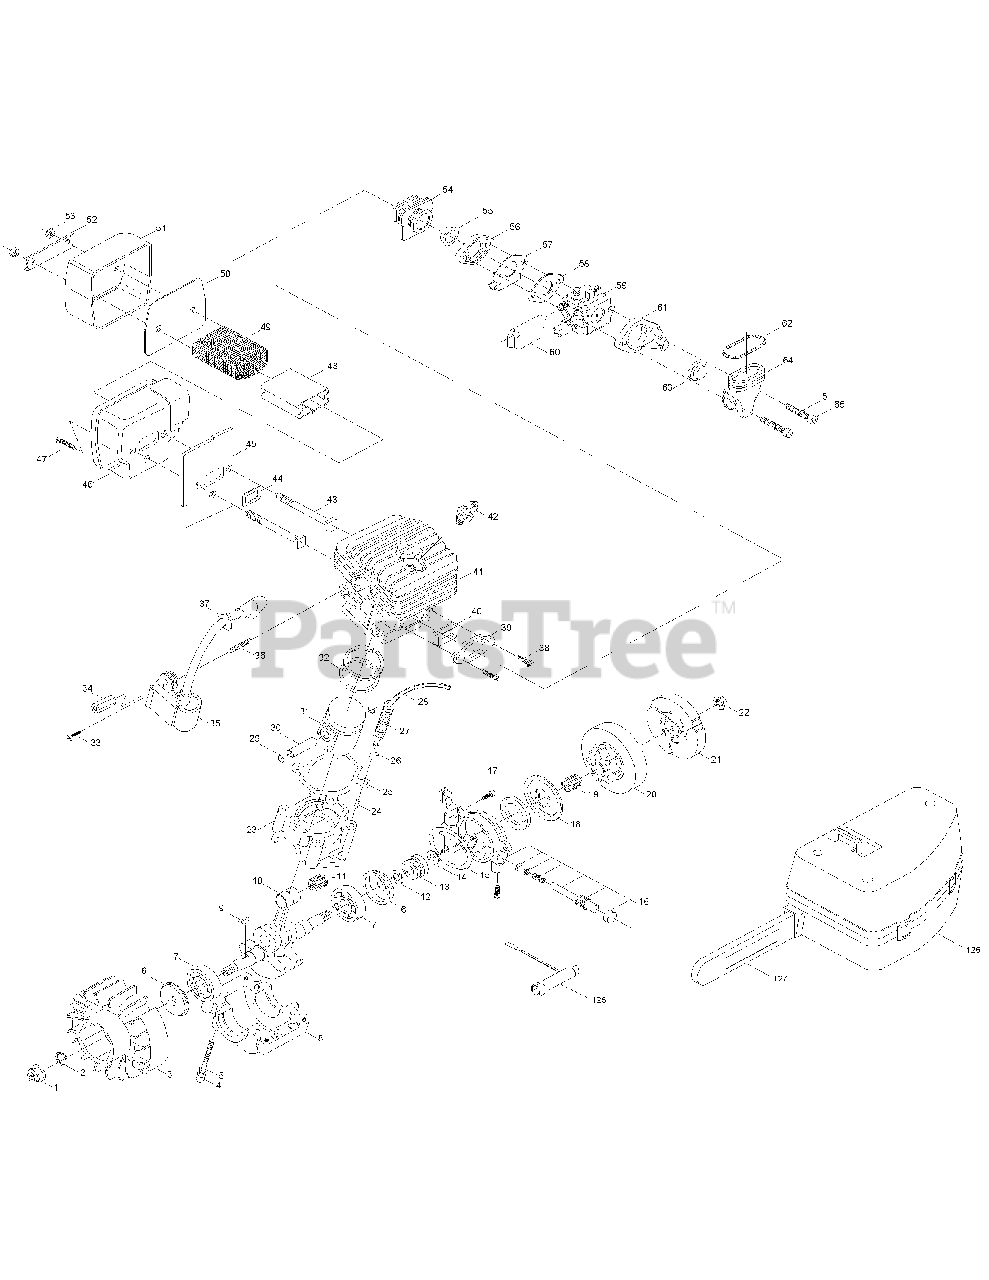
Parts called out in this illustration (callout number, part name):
8	CRANKCASE LOWER
10	C'SHAFT/C'ROD ASS'Y
13	GEAR, WORM
16	PUMP ASS'Y
20	DRUM SPRKT ASS'Y
21	CLUTCH ASS'Y
23	CRANKCASE UPPER
24	FITTING, PULSE LINE
26	CLAMP, WIRE HOSE
27	CONDUIT, FLEX
32	RING, PISTON
35	IGNITION ASS'Y
38	SCREW
39	FLANGE
42	SPARK PLUG
46	MUFFLER BODY ASS'Y
51	COVER, MUFFLER
52	LOCKPLATE
54	BOOT, CARBURETOR
59	CARBURETOR
67	STARTER ASS'Y
74	PRIMER, REMOTE
77	FILTER, FUEL
80	FUEL/OIL TANK ASS'Y
81	VALVE DUCKBILL
91	PLATE, FLANGE
93	20" CHAIN
96	CHAIN BRAKE ASS'Y
99	CHOKE ASS'Y
100	ROD, CHOKE
102	ISOLATOR ASS'Y
103	CABLE ASS'Y
107	RELEASE, TRIGGER
113	ISOLATOR ASS'Y
115	COVER ASS'Y, HANDLE
119	HANDLE ASS'Y
120	COVER ASS'Y
123	AIR CLEANER ASS'Y
126	CARRY CASE
